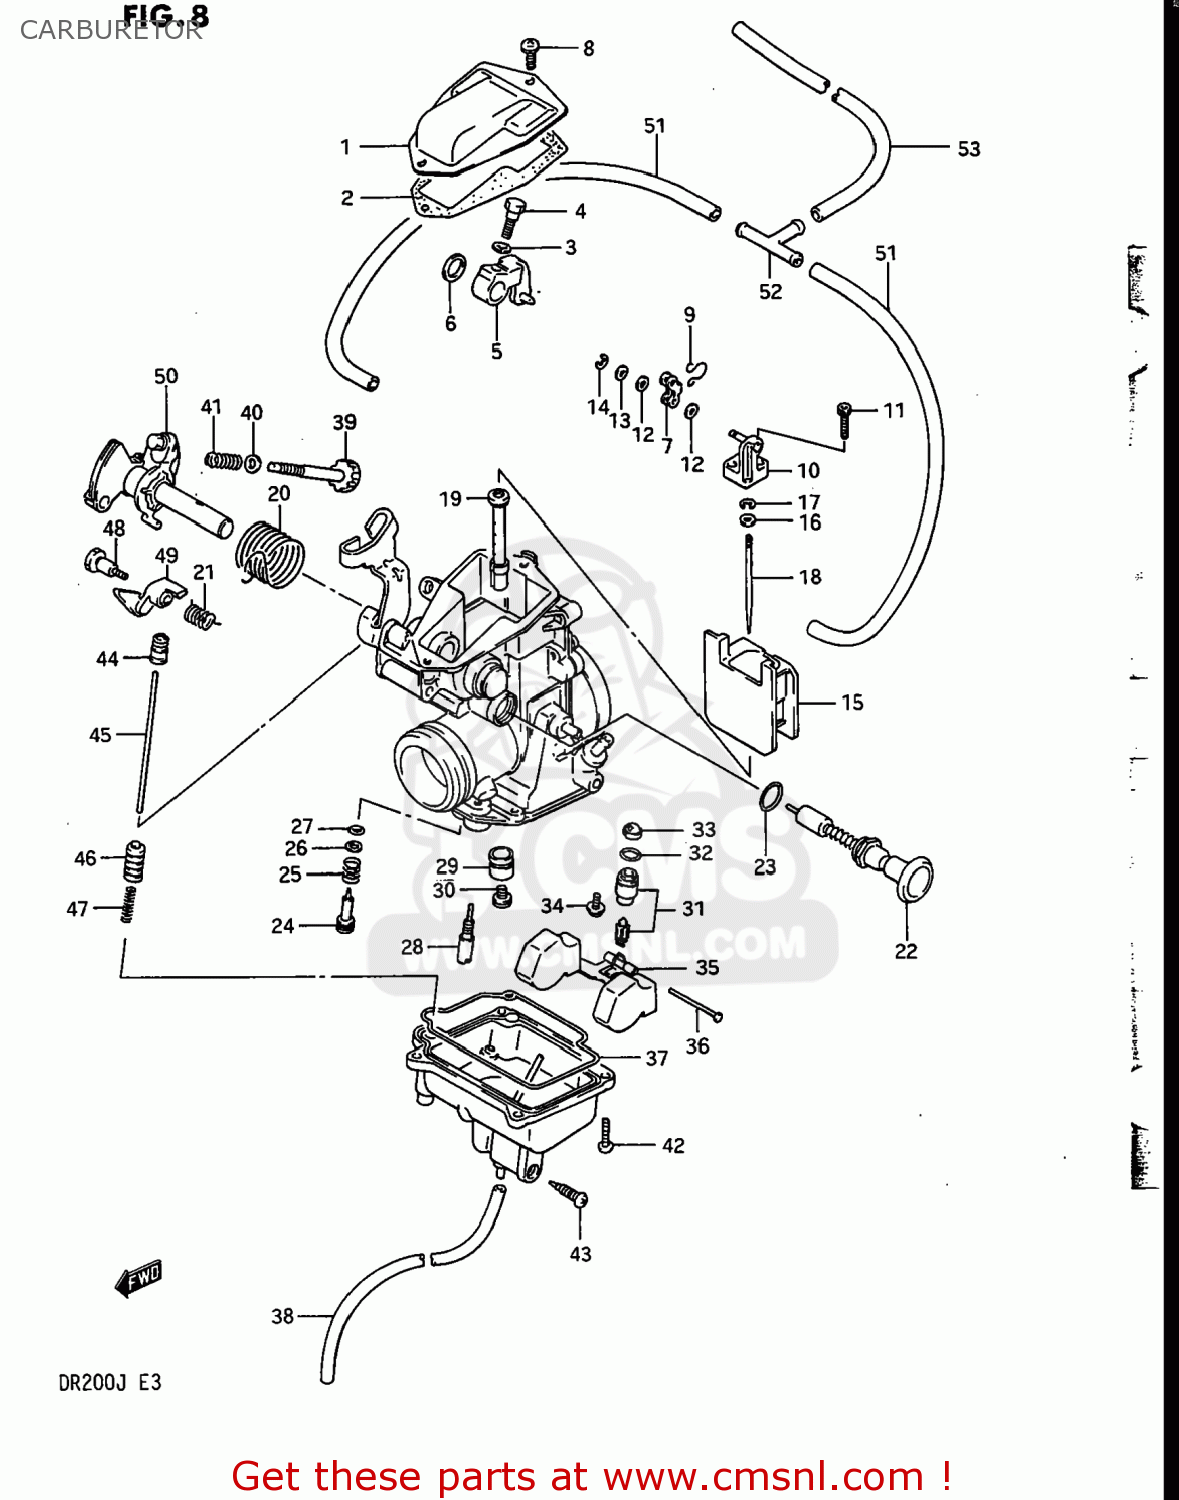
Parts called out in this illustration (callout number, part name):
1	COVER,CARBURETOR,TOP
2	GASKET,CARBURETOR TOP (NAS)
3	WASHER
4	BOLT
5	ARM,THROTTLE
6	RING,THROTTLE SHAFT
7	PLATE
8	SCREW
9	SPRING
10	CONNECTOR
11	SCREW
12	GASKET (NAS)
13	WASHER
14	E-RING
15	VALVE,THROTTLE
16	WASHER,JET NEEDLE
17	CLIP
18	NEEDLE,JET
19	JET,NEEDLE (P-6)
20	SPRING
21	SPRING,PLUNGER
22	PLUNGER ASSY
23	O RING
24	SCREW,PILOT
25	SPRING
26	GASKET
27	O-RING
28	JET
29	RING,MAIN JET FIXING
30	JET,MAIN(115)
31	VALVE ASSEMBLY,NEEDLE
32	O RING
33	FILTER
34	SCREW
35	FLOAT
36	PIN,FLOAT
37	O RING,FLOAT CHAMBER
38	HOSE
39	SCREW,THROTTLE STOP
40	WASHER
41	SPRING
42	SCREW
43	SCREW,DRAIN
44	BOOT, ACCELE PUMP ROD
45	ROD,PLUNGER
46	PLUNGER
47	SPRING
48	BOLT
49	LEVER
50	SHAFT ASSEMBLY
51	HOSE
52	JOINT,3 WAY
53	HOSE
